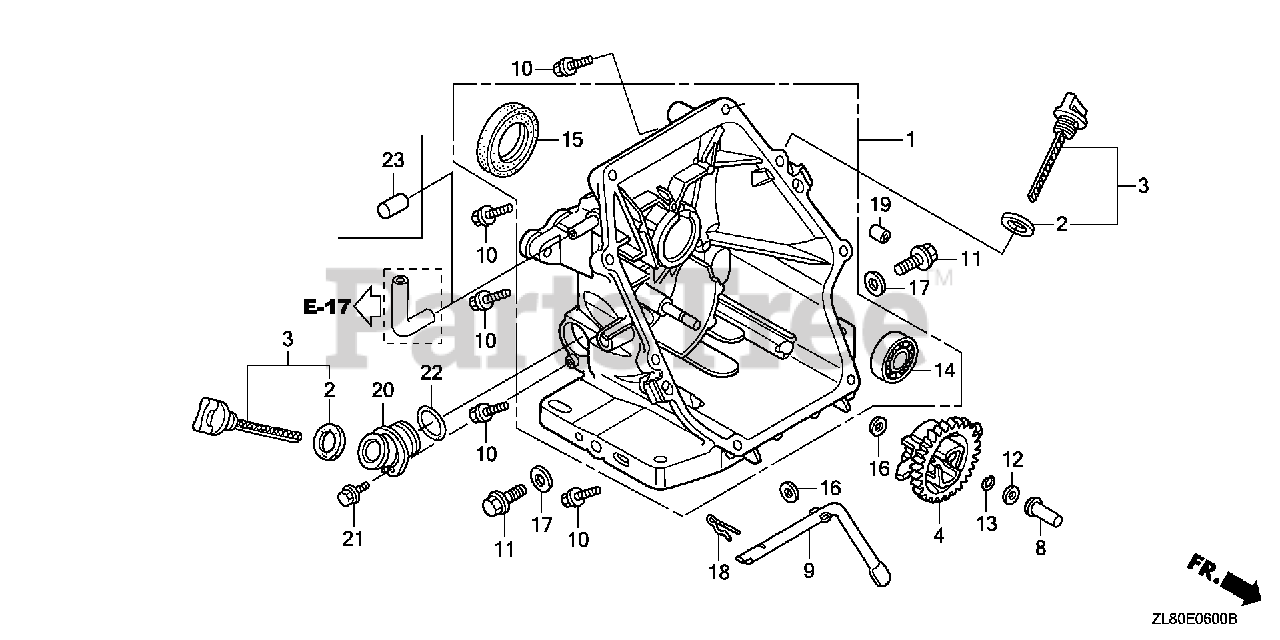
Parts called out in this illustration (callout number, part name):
1	COVER ASSY., CRANKCASE
2	GASKET, OIL FILLER CAP
3	GAUGE ASSY., OIL LEVEL
4	GOVERNOR ASSY.
8	SLIDER, GOVERNOR
9	SHAFT, GOVERNOR ARM
10	BOLT, FLANGE (6X25) (CT200)
12	WASHER, THRUST (6MM)
13	CLIP, GOVERNOR HOLDER
14	BEARING, RADIAL BALL (62/28)
15	OIL SEAL (28X41.25X6)
16	WASHER, PLAIN (6MM)
18	PIN, LOCK (8MM)
19	PIN, DOWEL (8X20)
